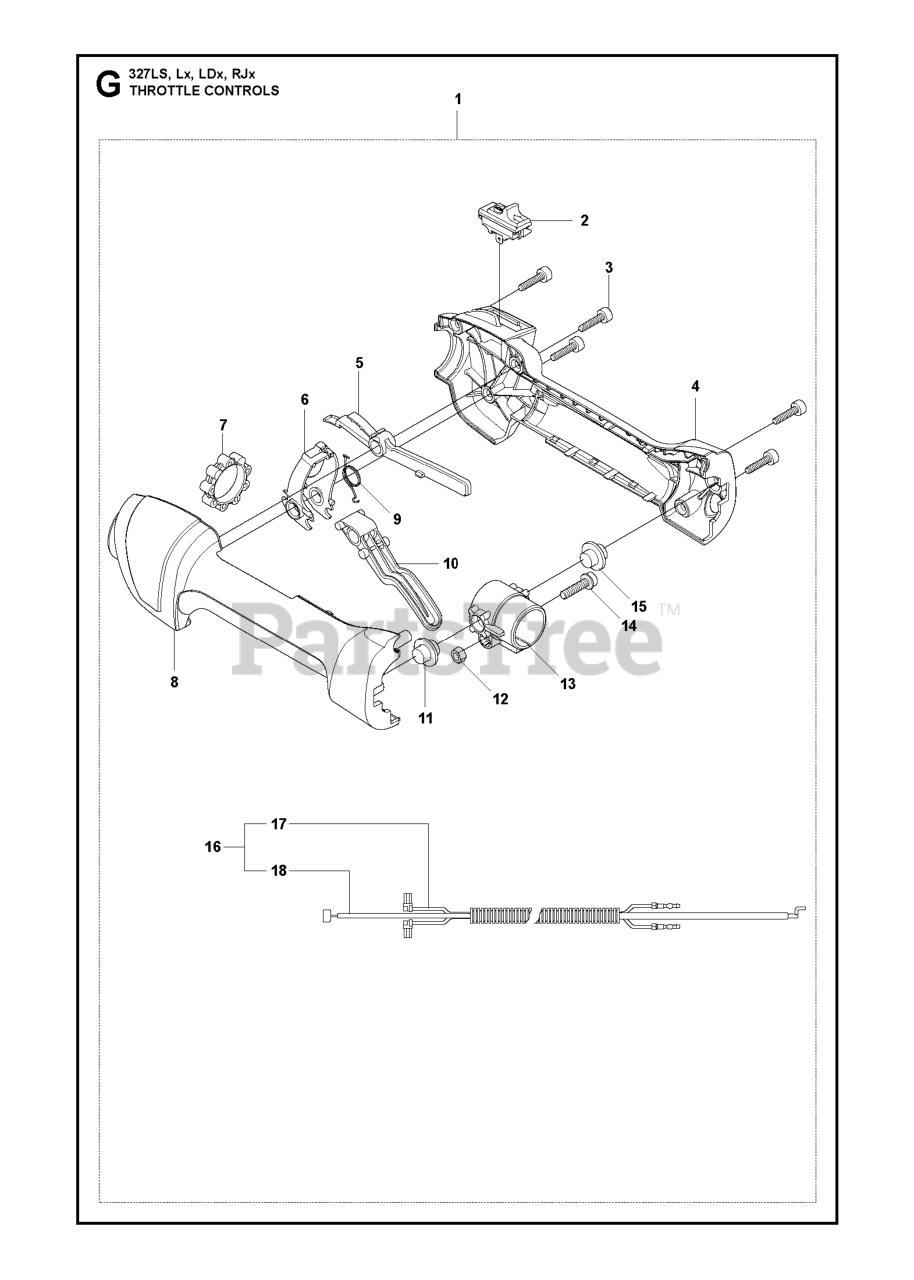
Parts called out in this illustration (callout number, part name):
1	ASSY THROTTLE CONTROL
2	STOP BUTTON
5	THROTTLE LOCK
7	VIBRATION DAMPER
9	RETURN SPRING
10	THROTTLE TRIGGER
11	VIBRATION ABSORBER
15	VIBRATION ABSORBER
17	SHORT CIRCUIT CABLE
18	THROTTLE WIRE ASSY
